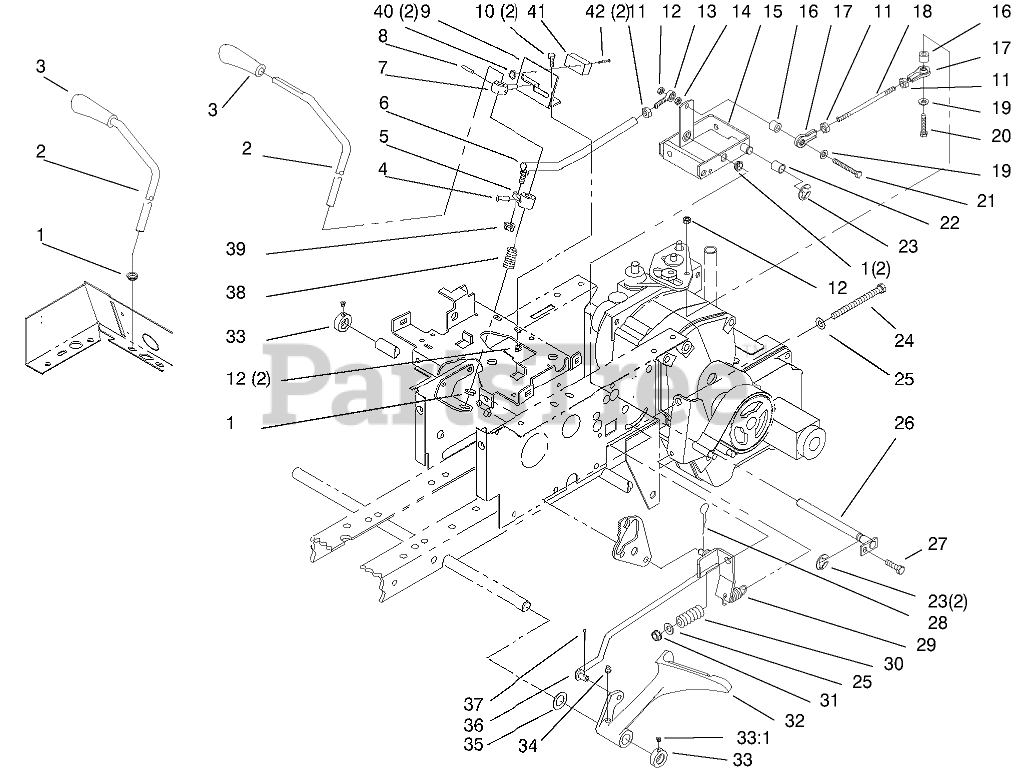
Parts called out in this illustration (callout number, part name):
1	NYLINER BUSHING
2	ROD-MOTION CONTROL
3	Knob
4	SPIROL PIN 7/32X7/8
5	ARM-CONTROL
6	ASSY-ROD & BALL JOINT
7	GUIDE-CONTROL
8	PIN-SPECIAL
9	Bracket-Control
10	SCREW-HH
11	NUT-JAM
12	NUT-LOCK, NI
13	ROD END, 1/4-28
14	NUT-HEX
15	Cam Comtrol
16	Spacer
17	ASSY ROD END
18	ROD-CONTROL
19	WASHER-FLAT
20	SCREW-HH
21	HHCS 1/4X2.25 FULL T
22	BEARING-CAM RETURN
23	RING-RETAINING, EXTERNAL
24	SCREW-HH
25	WASHER-FLAT
26	ASSY-ROD CAM PIVOT
27	Bolt
28	PIN-HAIR
29	SPRING
30	SPRING-COMPRESSION
31	NUT-LOCK, NI
32	Pedal-Brake
33	COLLAR
33:1	SCREW-HSH
34	FITTING-GREASE
35	WASHER
36	ASY BRAK RD WAR
37	PIN-COTTER
38	SPRING-COMPRESSION
39	NUT-LOCK
40	NUT-HEX
41	SWITCH - CLUTCH
42	SCREW-PPH
